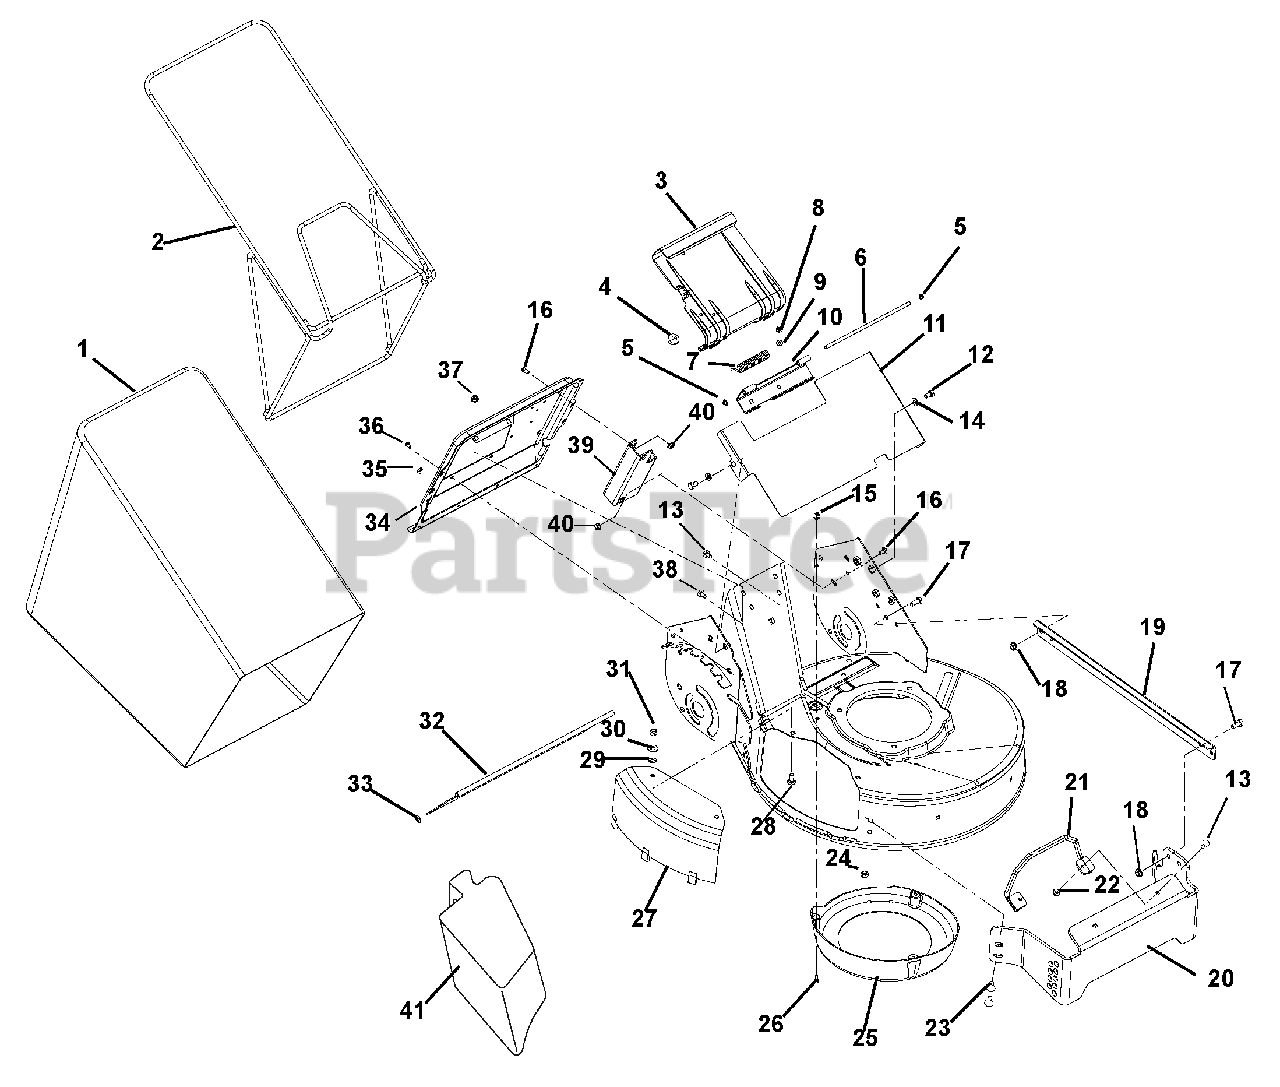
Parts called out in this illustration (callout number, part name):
1	BAG, CONSUMER BLACK 15 OZ/YD2
2	FRAME, WBLM BAGGER
3	CATCHER PLATE DOOR
4	BUTTON BUMPER
5	PUSH NUT, .25
6	DOOR PIN
7	SG-TORS .120X.68X3.09
8	@NUT-HEX .25-20 YWZC
9	WSHR-LK .250X.077 HVY YWZC
10	HINGE BASE
11	COVER
12	@SCR-TAP .25-20X.37 HWH YWZ TR
13	@BLT-RDHDSQNK .25-20X.75 G5YZ
14	@WSHR-LK .31X.078 REG YWZC
15	PLASTIC GROMMET
16	@BLT-RDHDSQNK .25-20X.50 G5YZ
17	@BLT-HEX .31-18X.75 GR5 YWZC
18	@NUT-LK-TOP-FLG .31-18 YWZC
19	ANGLE-SUPPORT
20	BUMPER,PRO 21"
21	ANGLE-SUPPORT
22	@NUT-LK-TOP-FLG .25-20 YWZC
23	@BLT-RDHDSQNK .31-18X.75 G5YZ
24	@NUT-SPNLK-FLG .312-18 YWZC
25	CENTER BAFFLE
26	SCR-TAP 10-16X.62 SLPH AB YWZC
27	COVER, SIDE DISCHARGE
28	BLT-RDHDSQSHK.31-18X.75 GR2 YW
29	NUT-PUSH .312
30	@WSHR-FL-STL.406X.812X.065 YWZ
31	@NUT-LK-NYL .312-18 YWZC
32	TRAILING SHIELD
33	NUT-PUSH .312
34	CATCHER PLATE
36	SCR-TAP 10-24X.375 TORX PHD YZ
37	@NUT-SPNLK-FLG .25-20 YWZC
38	@BLT-RDHDSQNK .25-20X.50 G5YZ
39	BKT,BAGGER SUPPORT
40	@NUT-SPNLK-FLG .25-20 YWZC
41	MULCH MASTER MULCHER ACCESSORY
